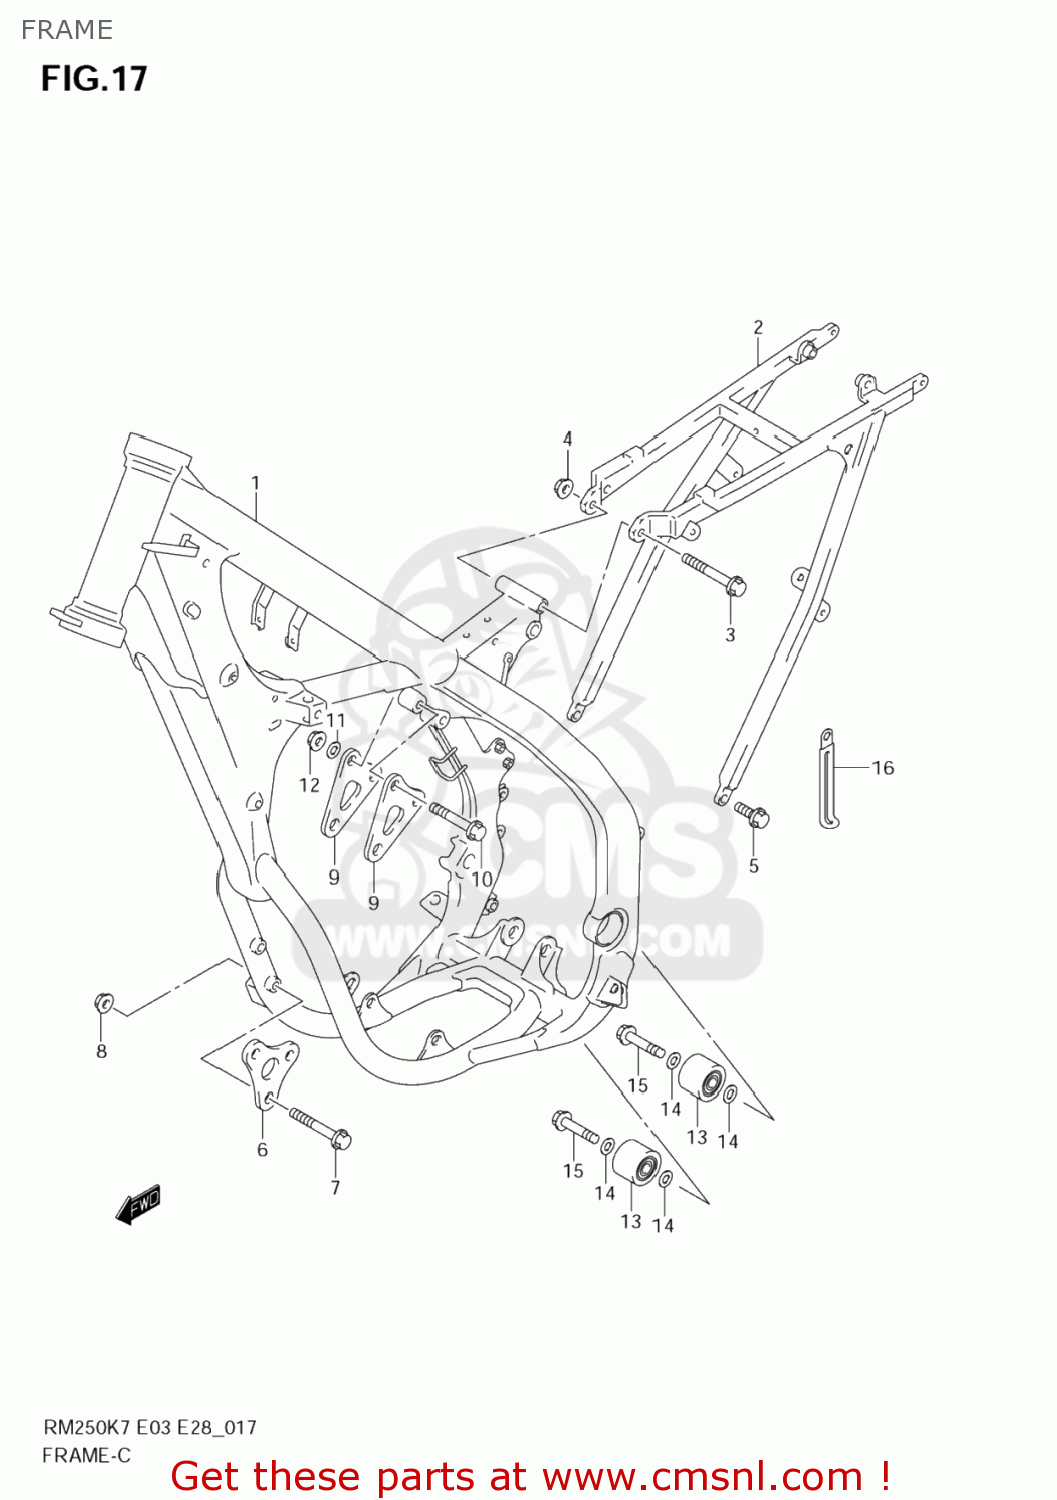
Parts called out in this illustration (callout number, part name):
1	FRAME(GRAY)
2	RAIL,SEAT
3	BOLT(8X100)
4	NUT
5	BOLT(8X16)
6	PLATE,ENGINE MOUNT FR
7	BOLT
8	NUT
9	PLATE,ENG MTG UPR
10	BOLT(8X45)
11	WASHER
12	NUT
13	ROLLER,CHAIN
14	SHIM(8X12X1)
15	BOLT(8X41)
16	CLAMP(L:65 T:0.8)
